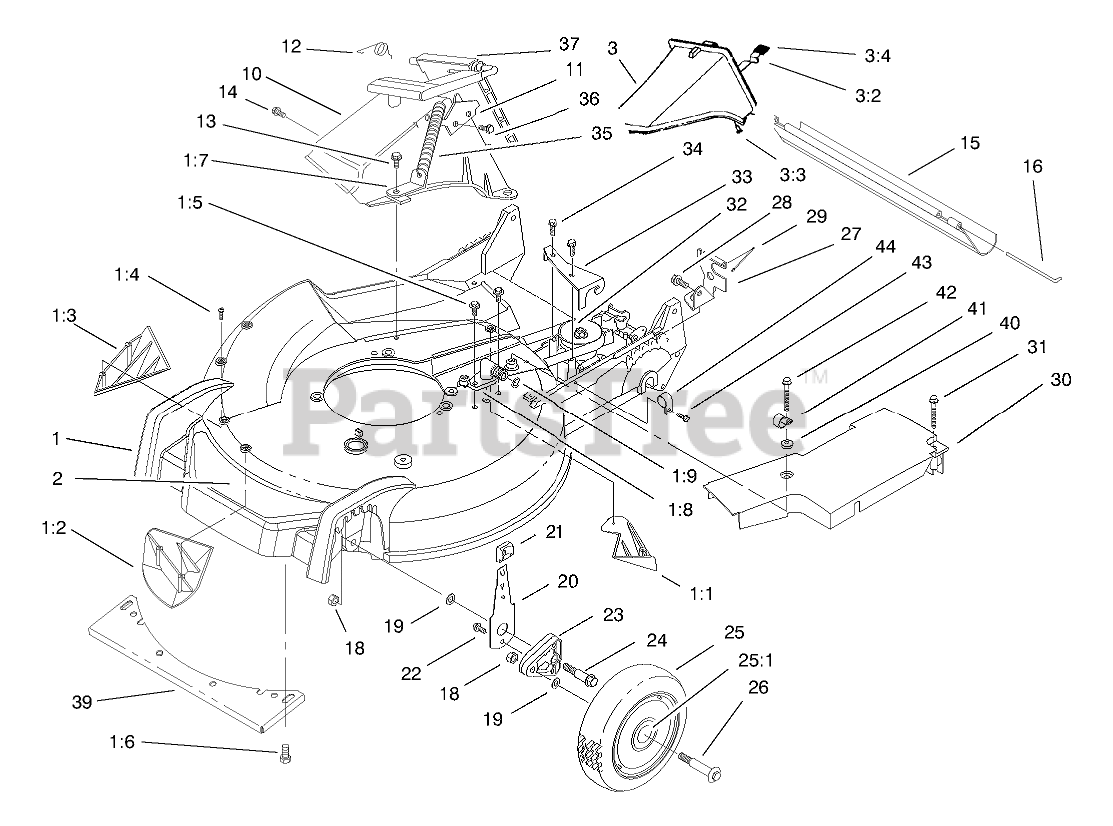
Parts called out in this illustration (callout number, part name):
1	HOUSING ASM
1:1	KICKER-REAR
1:2	KICKER-FRONT
1:3	KICKER-RH
1:4	SCREW-PPH
1:5	SCREW-HWH
1:6	SCREW-HWHTF
1:7	BRACKET-SPRING
1:8	FITTING-WASHOUT
1:9	O-RING
2	DECAL - DECK
3	DISCHARGE PLUG ASM
3:2	LATCH-PLUG, DISCHARGE
3:3	RIVET-HEAD, FLAT
3:4	GRIP-LATCH
10	TUNNEL-DISCHARGE
11	LATCH-PLATE
12	RETAINER-DOOR
14	SCREW AND WASHER ASM
15	SHIELD-TRAILING
16	ROD-SHIELD
18	NUT-LOCK
19	WASHER
20	FRONT SPRING ARM ASM
21	KNOB-ARM
22	SCREW-HWH
23	ARM-PIVOT, FRONT
24	BOLT-SHOULDER
25	Wheel-ASM
25:1	BUSHING
26	BOLT-WHEEL
27	Bracket-Adj. Trac
28	SCREW-HWHTF
29	RETAINER-CABLE
30	COVER-BELT
31	SCREW-HHFTF
32	GEARCASE ASM
33	Bracket-Guide
34	SCREW-HWHTF
35	SPRING-DOOR
36	SCREW-PLASTITE
37	DISCHARGE DOOR ASM
39	Shield-front
40	WASHER
41	CLAMP-CABLE
42	SCREW-SPECIAL
43	SCREW-HWH
44	CLAMP-CABLE
